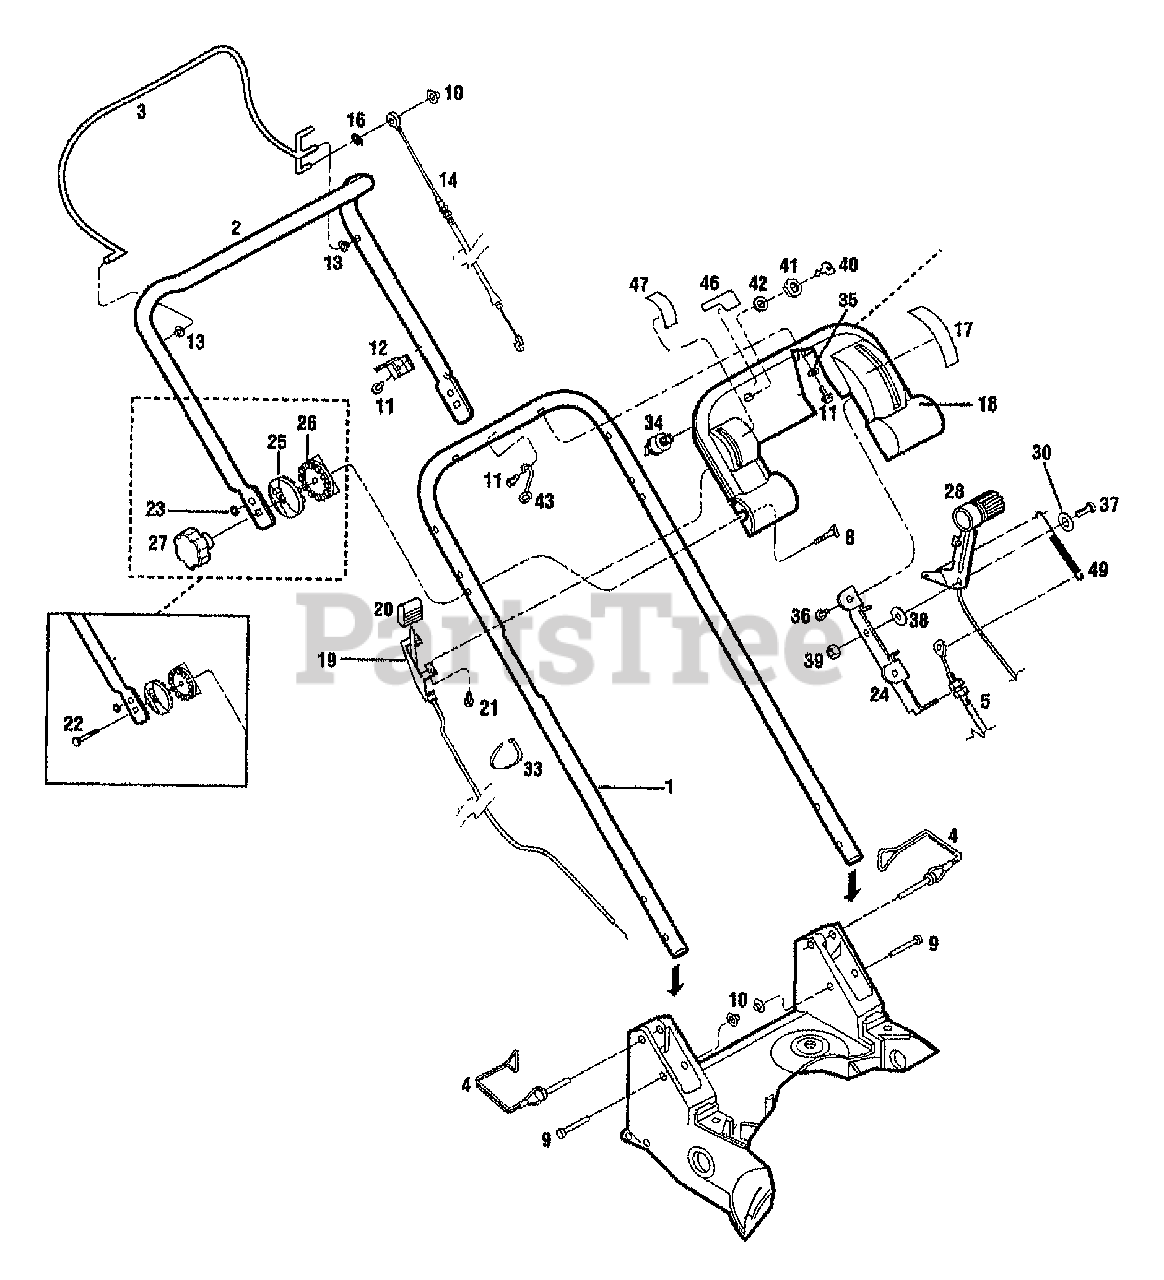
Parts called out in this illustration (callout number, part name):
1	HANDLEBAR-LOWER PNT
2	HANDLEBAR-UPR PNT
3	BAIL-CONTROL VINYL COATED {34322,34322C, 34323,34323
3	WELD BAIL {34345,34346}
4	PIN-LK SQ. BAIL
5	CABLE-DRIVE CONTROL
6	THIS REF. NO. NOT USED
7	THIS REF. NO. NOT USED
8	SCR-CURVED HD 5/16-18X2.0
9	PIN-CLEVIS ( @DEPL)
10	CAP-PUSH .312
11	SCR-FLANGE 1/4-20X3/4 GR5
12	BRKT-CONTROL CABLE
13	BUSHING-PLASTIC (BAIL)
14	CABLE-ENGINE BRAKE
15	THIS REF. NO. NOT USED
16	GRIP-RING EXT .312 ID
17	DECAL-WHEEL DRIVE
18	CONSOLE-T/B NGMM
19	CABLE-THROTTLE {34322,34322C,34323,34323C}
19	CONTROL-THROTTLE {34345,34346}
20	KNOB-WHEEL DRIVE CABLE
21	SCR-M10-16X.88 SPECIAL
22	THIS REF. NO. NOT USED
23	RETAINER .25
24	SUPT-CONTROL DRIVE
25	HANDLE ADJUSTER QUADRANT-OUTER
26	HANDLE ADJUSTER QUADRANT-INNER
27	KNOB-HANDLEBAR
28	ASSM-ARM CONTROL
29	THIS REF. NO. NOT USED
30	WASHER-BELLEVILLE
31	THIS REF. NO. NOT USED
32	THIS REF. NO. NOT USED
33	TIE-CABLE (REUSABLE)
34	SWITCH
35	WASHER-.78X.25X.08 ZP @DEP
36	SCR 1/4-15X.88 SPECIAL
37	SCR-RH 1/4-20X.75
38	BUSHING-NYLON
39	NUT-LK 1/4-20
40	KEYS-IGN T/BLAZER 1 PAIR
41	NUT-HEX/JAM 5/8-32 ZP
42	WASHER-LK 5/8 INT TOOTH
43	GUIDE-ROPE
44	THIS REF. NO. NOT USED
45	THIS REF. NO. NOT USED
46	DECAL-ELEC START
47	DECAL-THROTTLE {34322,34322C,34323,34323C}
47	DECAL-THROTTLE CONTROL {34345,34346}
49	SPRING-EXTENSION
